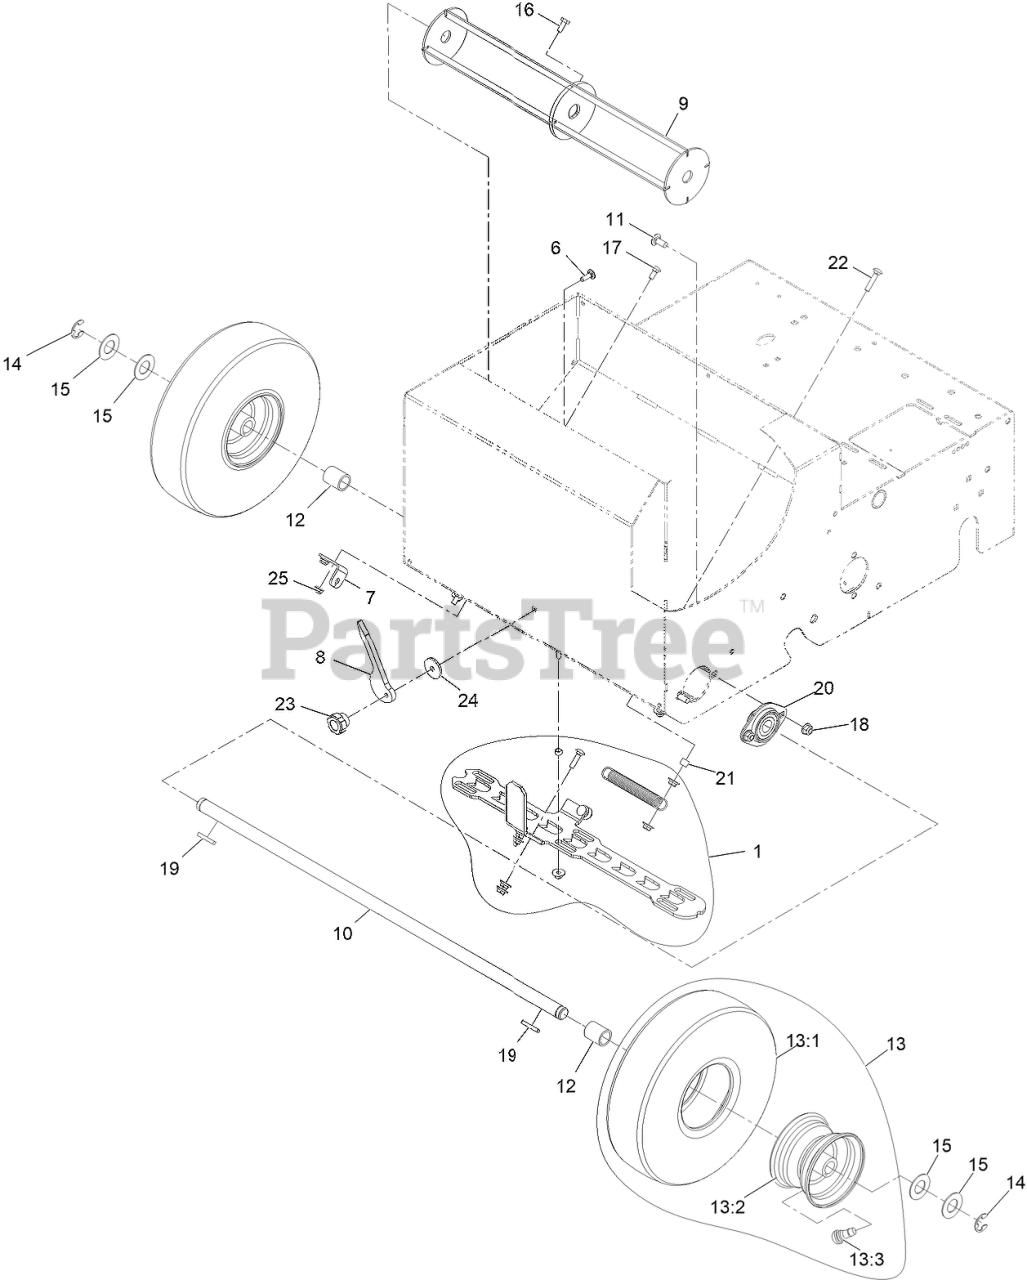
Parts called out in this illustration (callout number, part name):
1	SEED GATE KIT
6	BOLT-CARR
7	BRACKET-FLOW, SEED
8	GAUGE-FLOW, SEED
10	AXLE-FRONT
11	SCREW-CARR
13	WHEEL ASM
13:2	WHEEL-RIM
13:3	VALVE
15	WASHER-FLAT
16	SCREW-HH
17	SCREW-CARR
18	NUT-HF, NI
19	KEY-SQUARE
20	BEARING
22	SCREW-CARR
23	KNOB-CHUTE
24	WASHER
